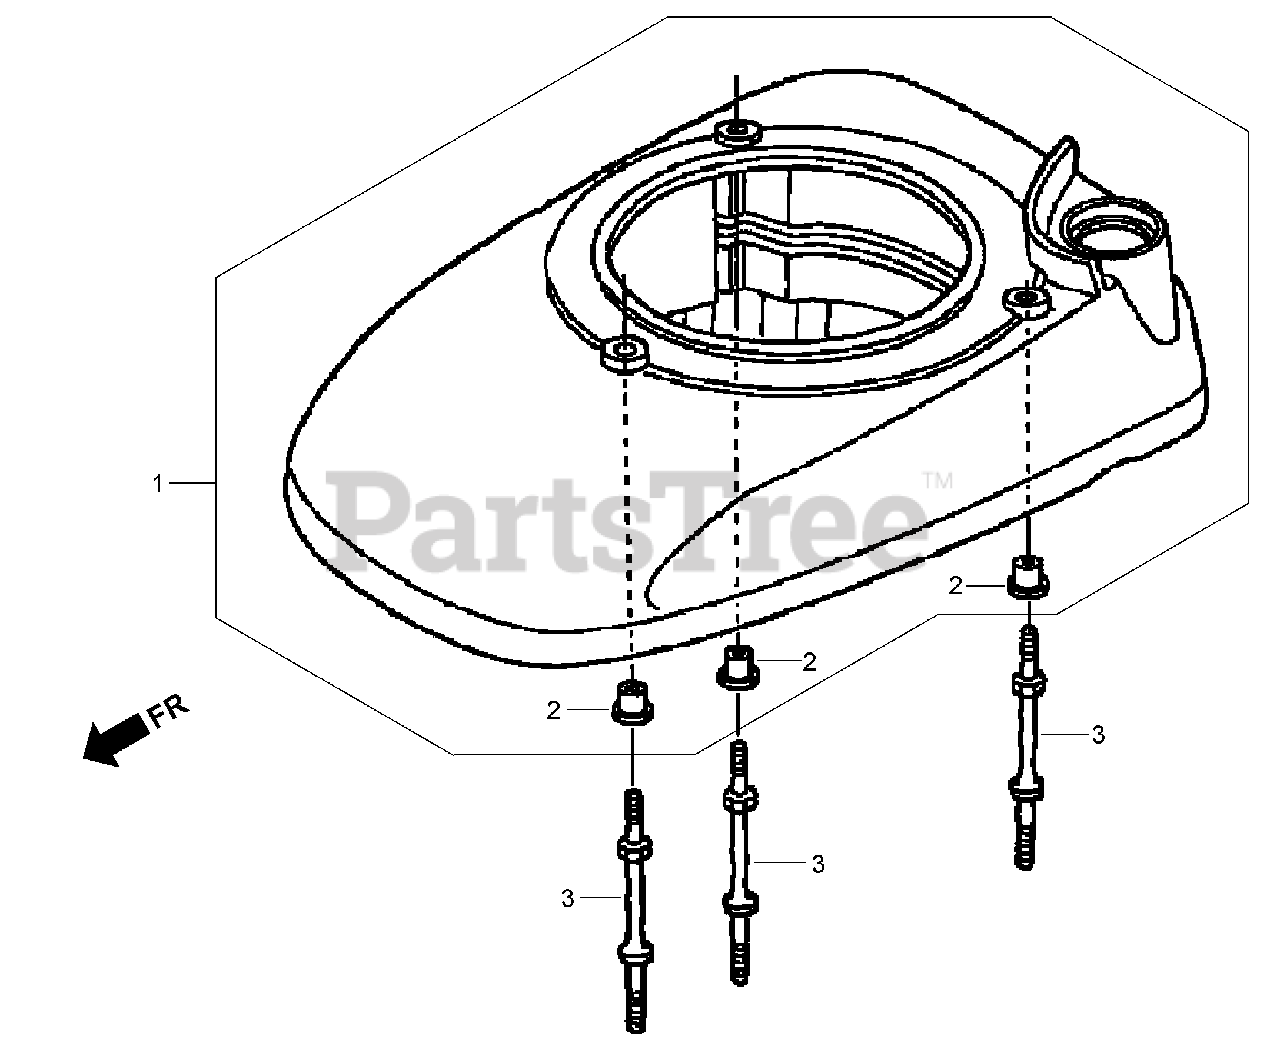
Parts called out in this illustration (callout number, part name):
1	COVER-FAN, N H1 (BLACK)
1	COVER-FAN, R280 (POWER RED)
2	COLLAR-COVER, FAN
3	BOLT-STUD (H T 42.5MM)
